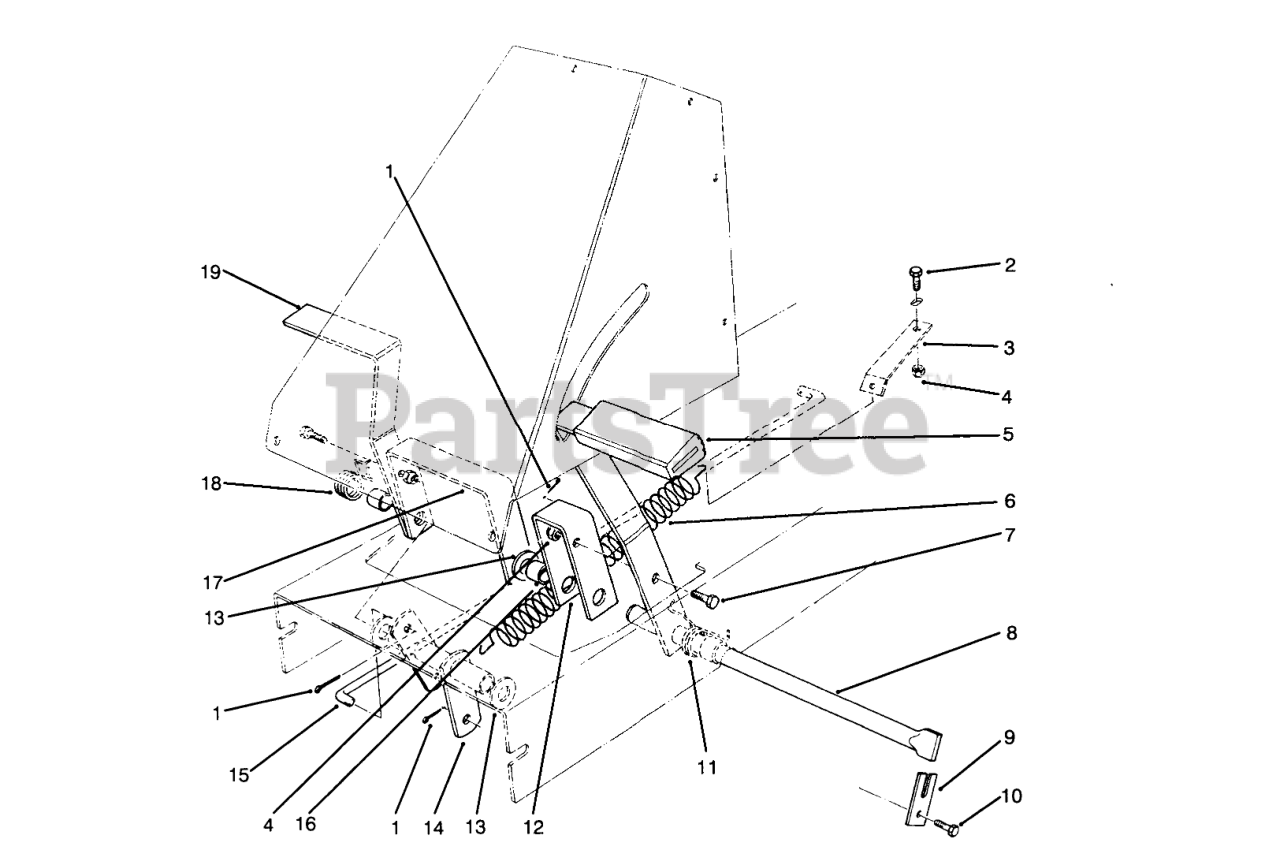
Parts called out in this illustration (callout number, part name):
1	PIN-COTTER
2	SCREW-HH
3	BRKT-SPRING RET
4	NUT-LOCK, NI
5	PAD-PEDAL
6	SPRING-EXTENSION
7	SCREW-HH
8	SHAFT-PEDAL PIVOT
9	RETAINER-SHAFT
10	SCREW-HH
11	SPRING-TORS CLUTCH
12	Bracket-Clutch Pedal
13	WASHER-FLAT
14	Pivot Tube
15	ROD-ENGAGE
16	SPACER-PEDAL
17	Bracket-Brake Pedal
18	SPRING-TORS BRAKE
19	Pedal
